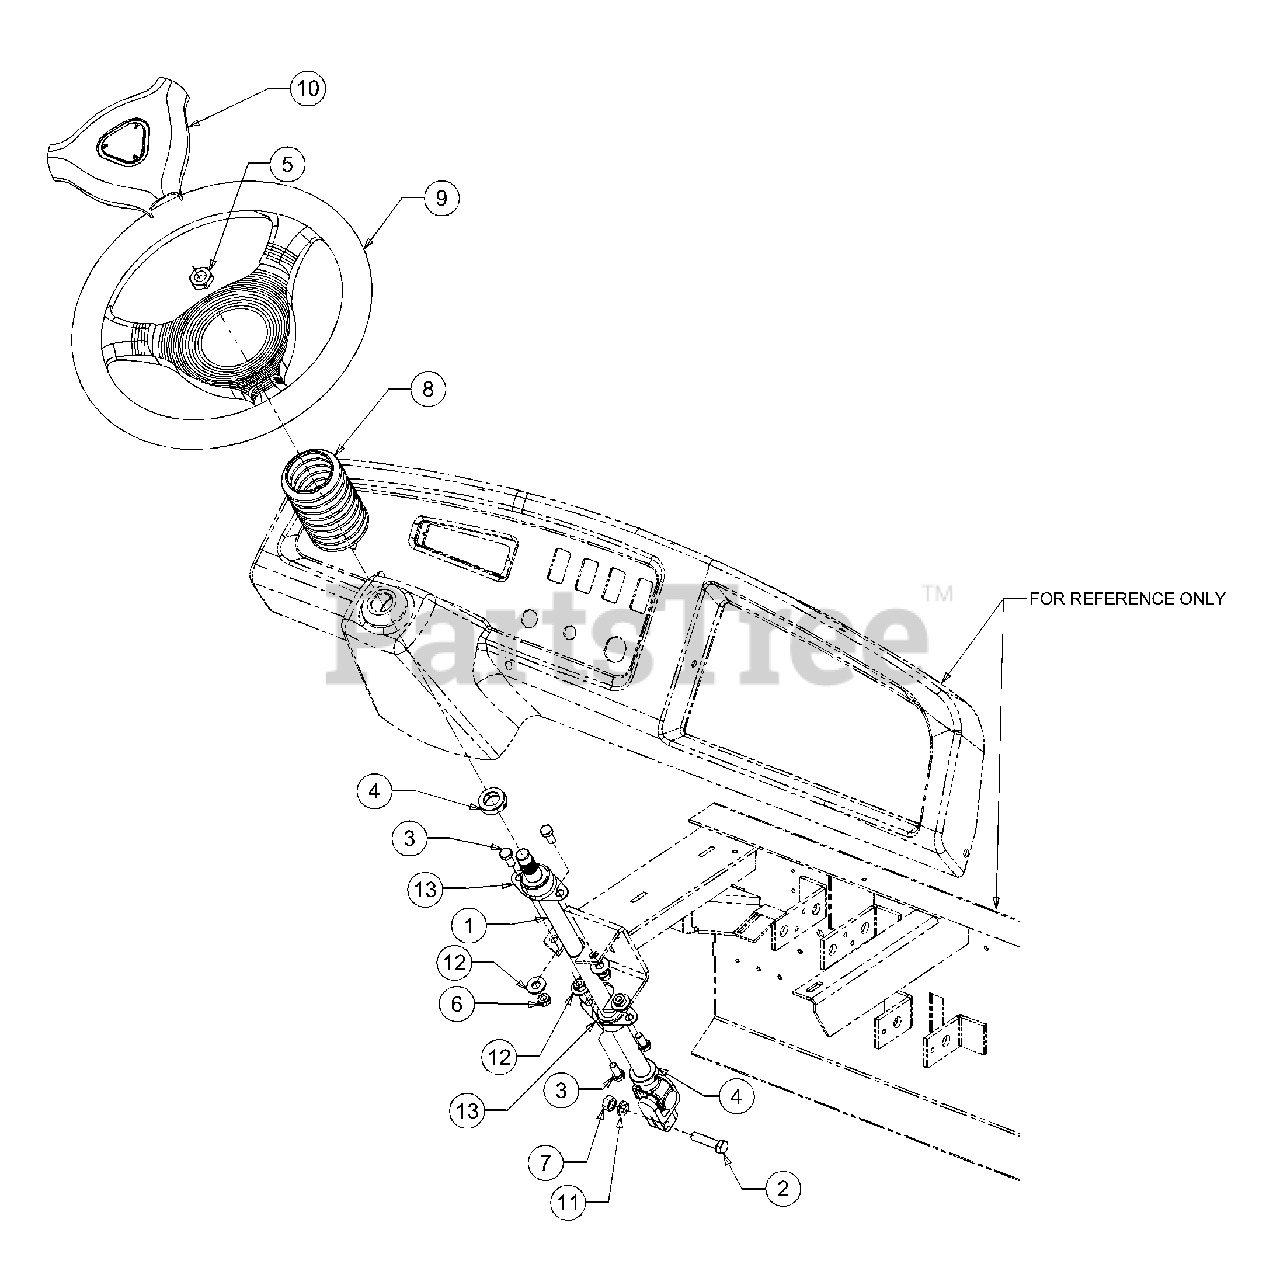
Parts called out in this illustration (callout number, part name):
1	Shaft Assembly, Steering
2	Hex Screw, 3/8-16, 1.50, Gr5
3	Hex Screw, 5/16-18, .75, Gr5
4	Collar, .75
5	Nut, Hex, M16-2, Class 8
6	Nut, Hex Lock, 5/16-18
7	Nut, Hex, 3/8-16, Gr8
8	Bellow, Steering, 4.75 Lg
9	Steering Wheel, Three-spoke
10	Cover, Steering Wheel, Soft Grip
11	Washer, Lock, 3/8, Regular Duty
12	Washer, Flat, .385 ID x .870 OD x .092
13	Bearing, Flange, .75 ID, Self-Aligning
